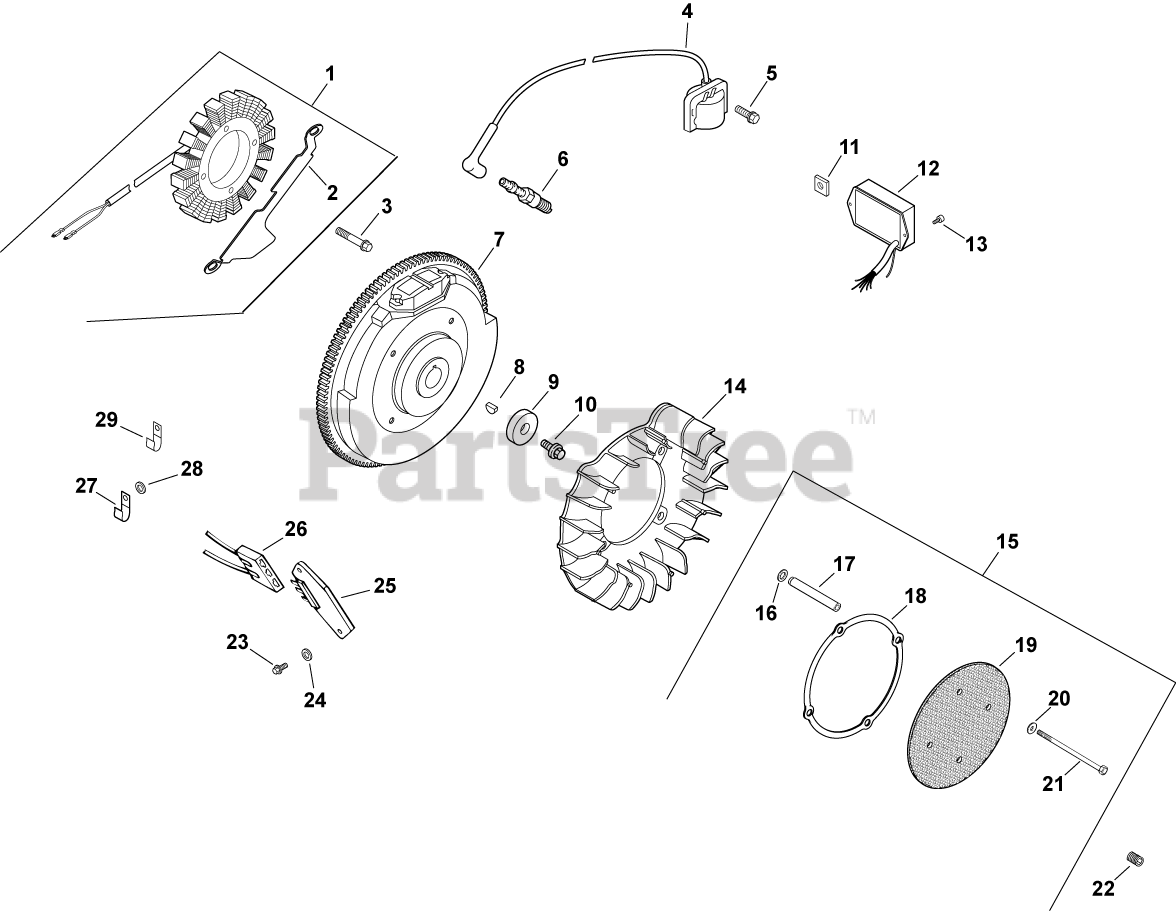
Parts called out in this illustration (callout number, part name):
1	STATOR KIT - USE 237878-S
2	BRACKET, STATOR WIRE-USE 24 126 139-S
3	SCREW, M5X0.8X25 - (#25086402S)
5	SCREW, SKT THD FRM M5X0.8X25
7	FLYWHEEL, PAINTED-USE 24 025 57-S
8	KEY, 3/16" X 5/8"
9	WASHER, FLAT 13/32"
10	SCREW, FLG M10X1.5X45 - (#25086361S)
11	NUT, PLASTIC
12	MODULE, SPEED ADVANCE
13	SCREW, PHL HD #11-16X1/2"
15	KIT, CHOPPER SCREEN
16	WASHER, SPRING 10 MM
18	RING, SUPPORT USE 25 141 08-S
19	SCREEN, GRASS-USE 24 162 41-S
20	WASHER, FLAT 1/4" (O.D. 5/8")
21	SCREW, SOCKET TRUSS HD CAP
22	SCREW, SKT SET #10-24X1/4"
23	SCREW, PHL HD #11-16X7/8"
24	WASHER, FLAT 3/16"
26	CONNECTOR, BODY (KM)-USE 25 155 41-S
27	CLIP, CABLE
28	WASHER, FLAT 1/4" (O.D. 1/2")
